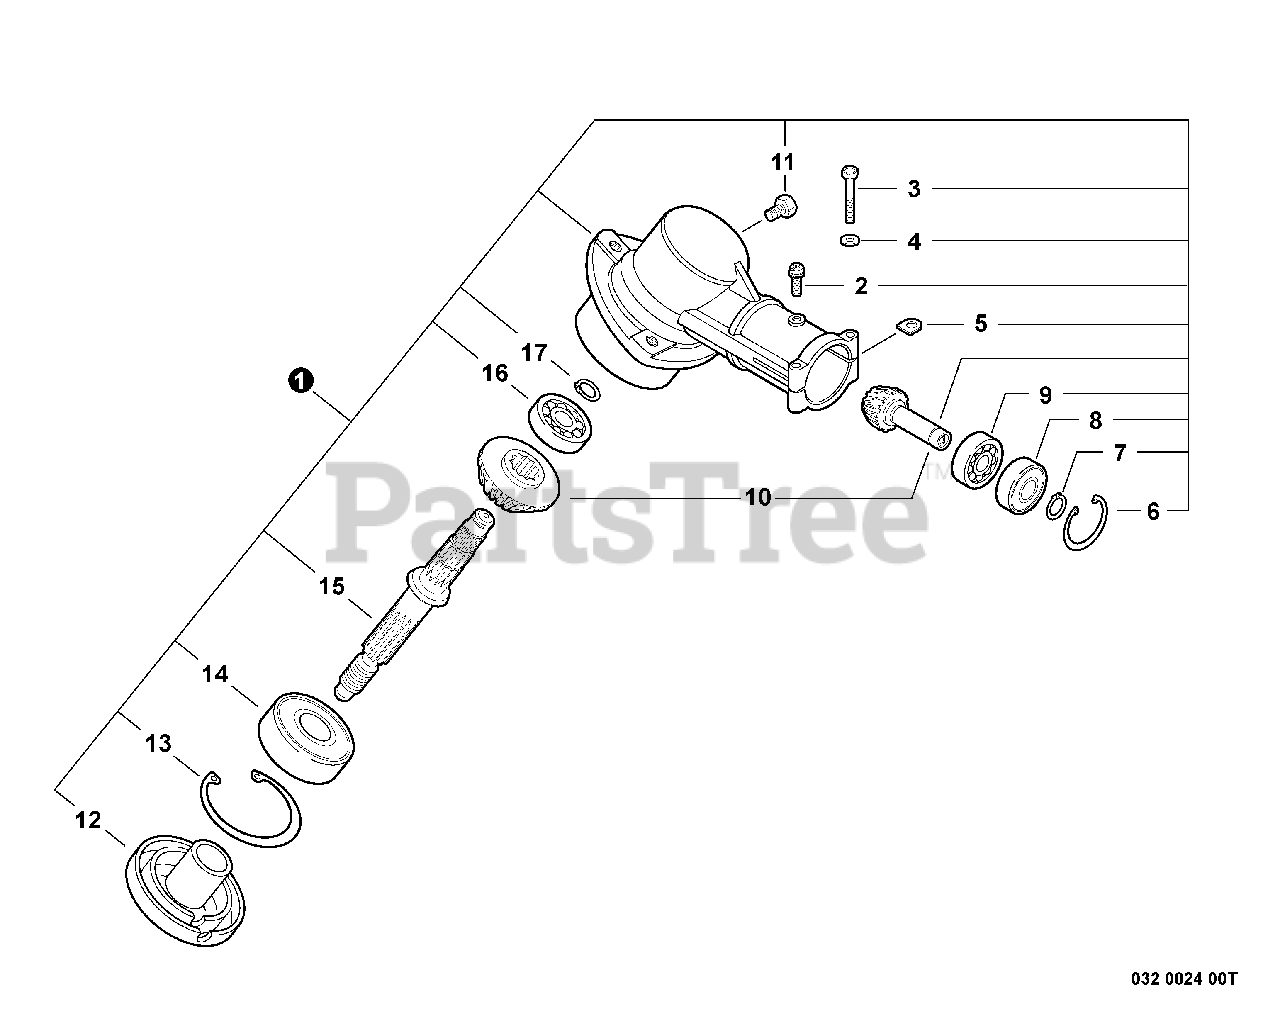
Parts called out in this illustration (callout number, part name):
1	GEAR CASE ASSY
2	SCREW 5×12
3	BOLT 5×35 SP
4	WASHER, FLAT 5.5×10×0.8
6	RING, SNAP Ø22
7	RING, SNAP Ø10
8	BEARING, BALL 6900Z
9	BEARING, BALL 6900
10	GEAR SET
11	BOLT M8×8
12	PLATE, ADAPTOR - UPPER
13	RING, SNAP Ø42
14	BEARING, BALL 6302
15	SHAFT, GEAR
16	BEARING, BALL 629
17	RING, SNAP Ø12
